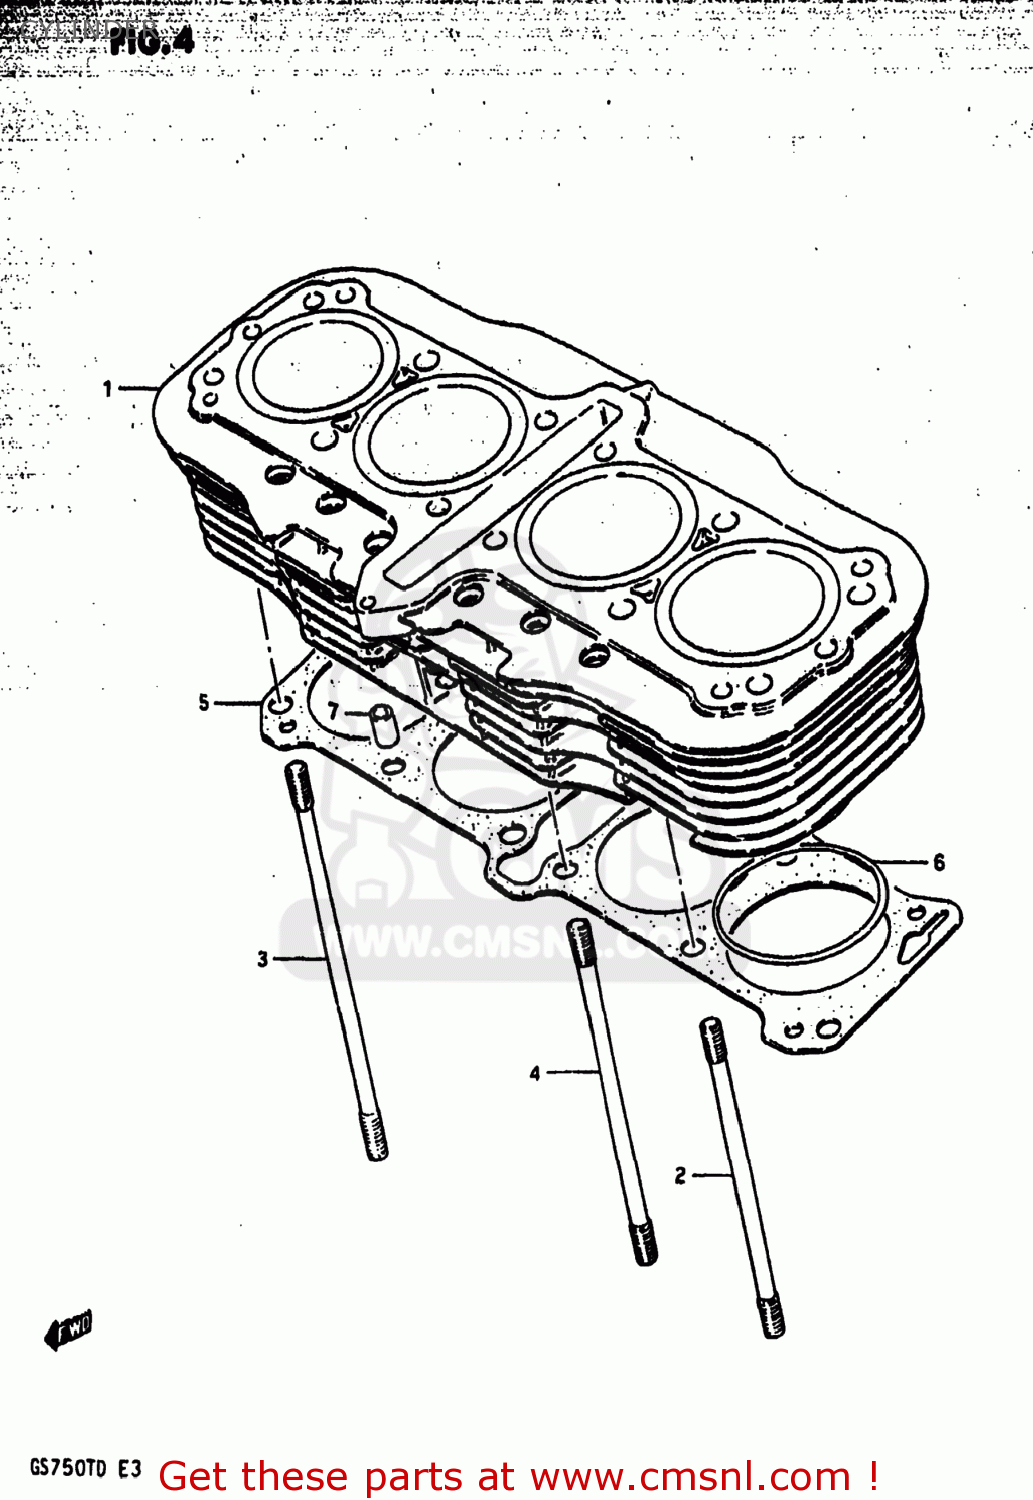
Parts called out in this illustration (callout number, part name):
1	CYLINDER
2	STUD
3	STUD
4	STUD
5	GASKET,CYLINDER (MCA)
6	O RING(D:2,ID:70)
7	PIN
